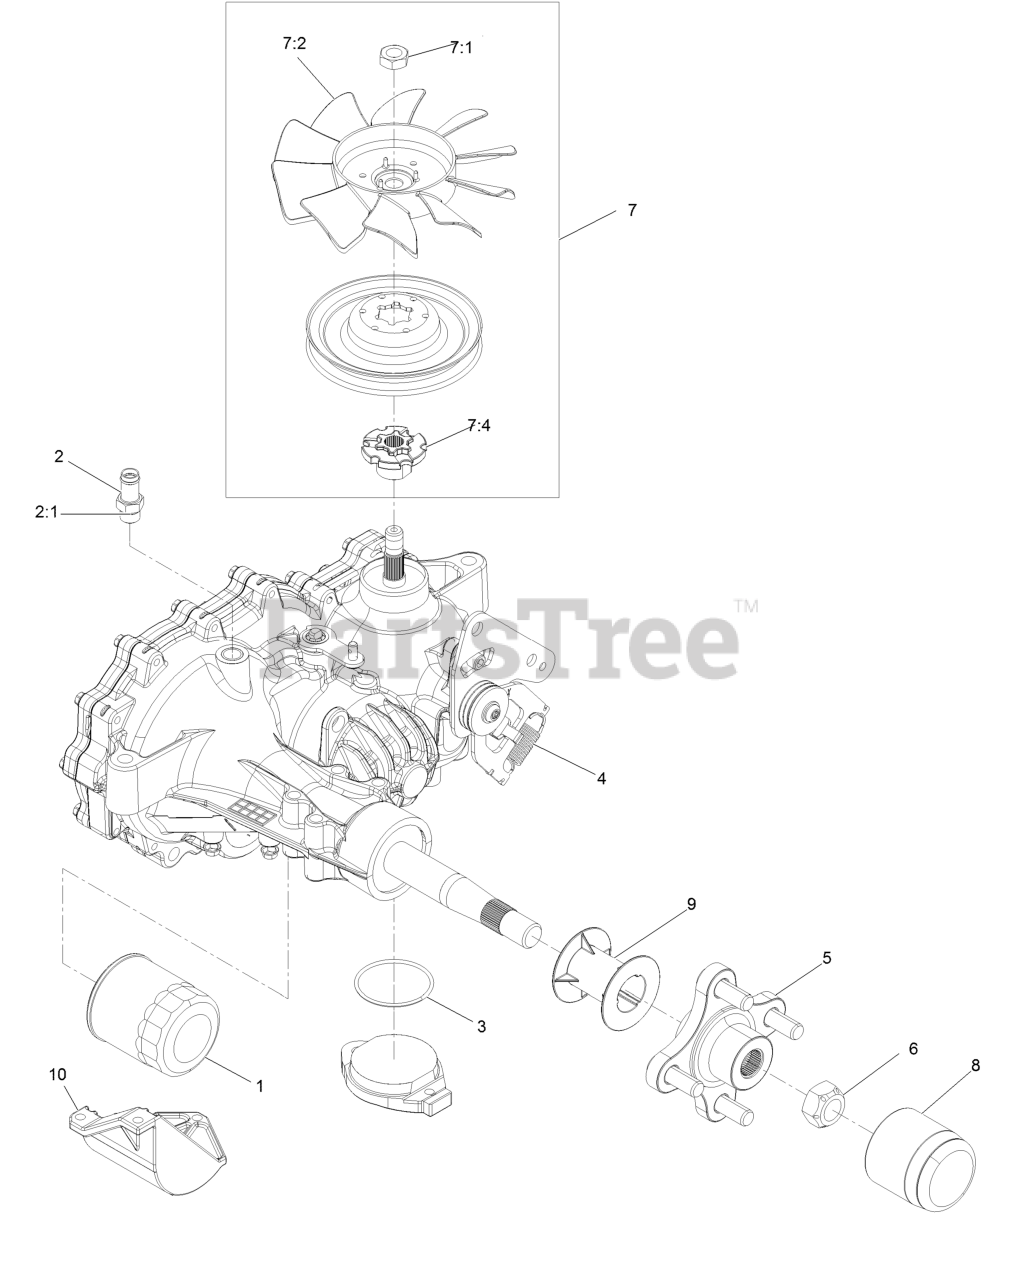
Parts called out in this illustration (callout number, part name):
1	Filter-Hydraulic
2	Adapter-Straight
2:1	O-Ring
3	O-Ring-Charge Seal Cover
5	Hub-Offset
6	Nut-Hub
7	Fan And Pulley Kit
7:4	Hub-Pulley
8	Cap-Axle, Long
9	Tube-Axle
10	Guard-Filter, RH
99	Seal Kit
